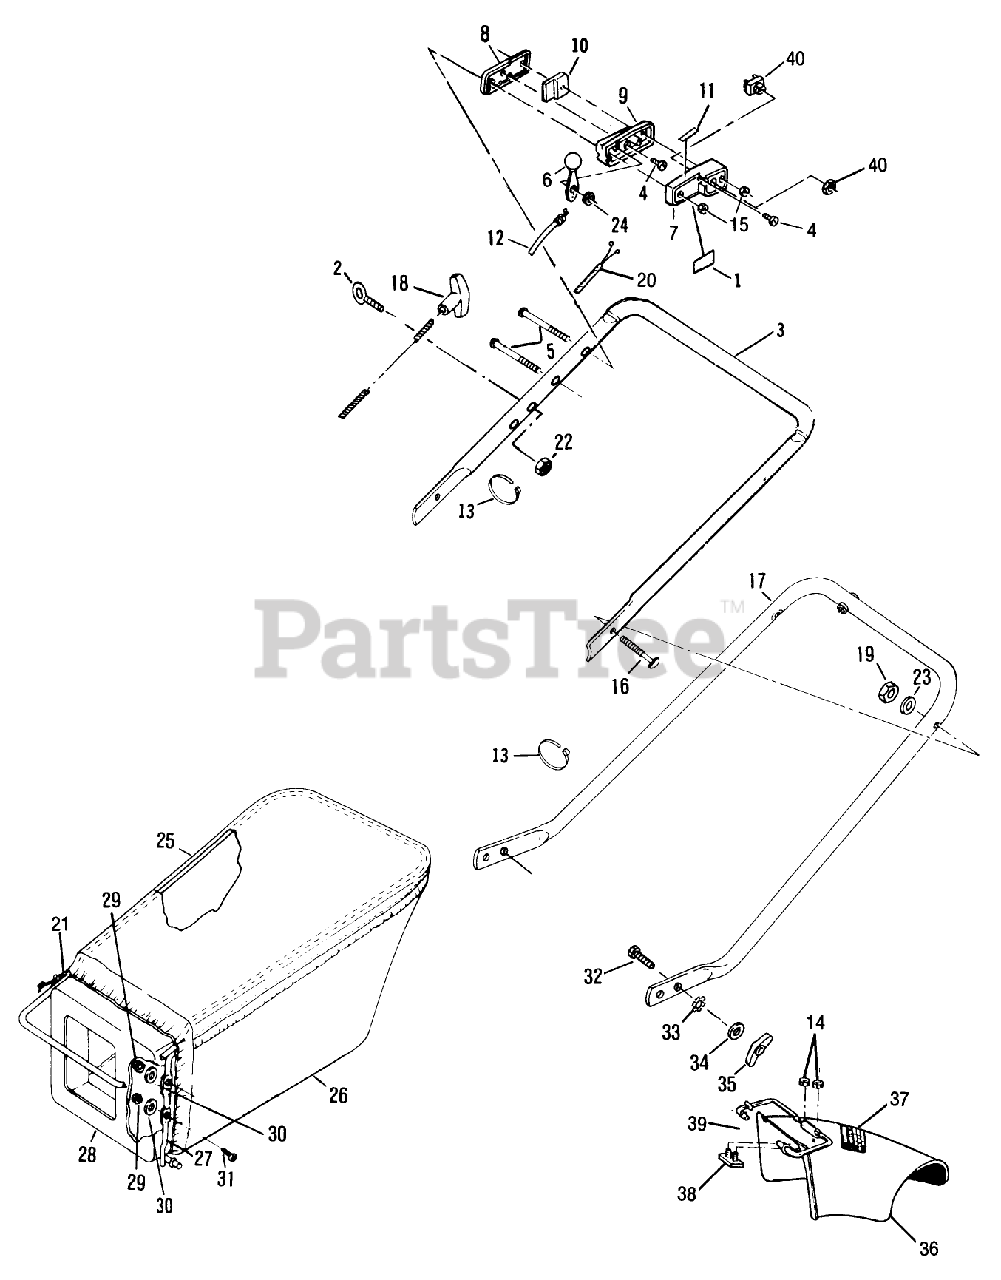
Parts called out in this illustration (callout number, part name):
2	EYE BOLT WAS MFG
4	SCREW
5	SCREW
6	LEVER&KNOB AY WES
8	OUTER CONTROL CASE
12	T/CABLE WESCON
14	LOCKNUT E
15	NUT C/LOCK E
17	HANDLE SECTION
18	HANDLE START UM&D
19	NUT-LOCK F
22	LOCKNUT E
23	WASHER-CURVED
24	WASHER-SPRING
25	HANGER BAG TROX
28	BAG ADAPTOR PL
29	LOCKNUT E
30	WASHER
34	WASHER
35	NUT-WING
39	LATCH BAR ARGO
